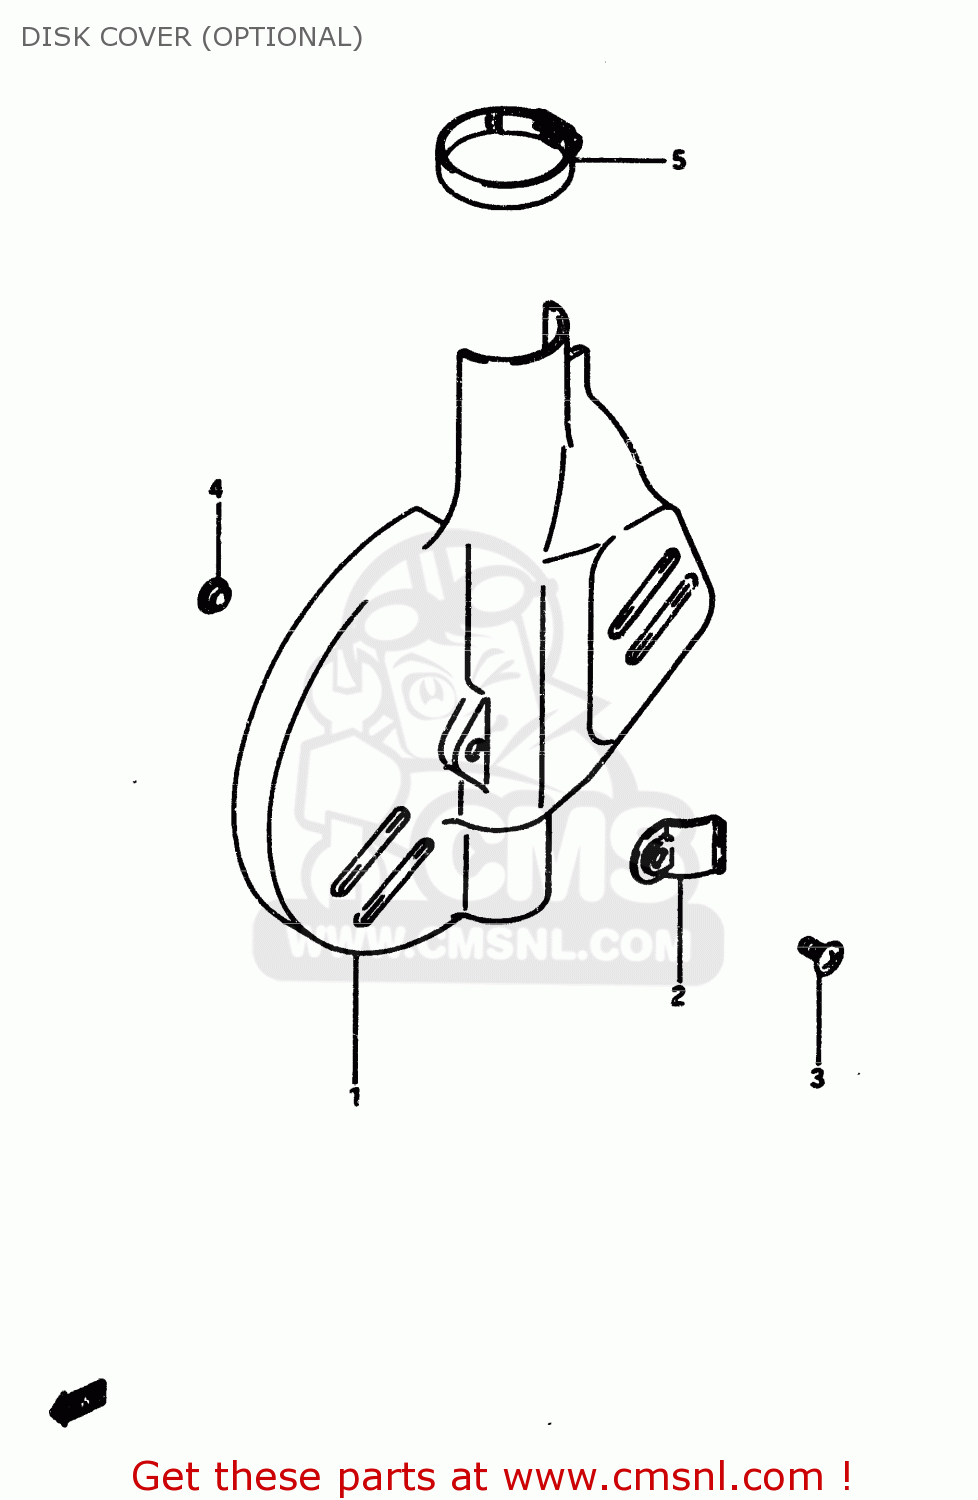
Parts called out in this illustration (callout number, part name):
1	COVER,FRONT BRAKE DISC
2	PLATE
3	SCREW(8X12)
4	WASHER
5	CLAMP
